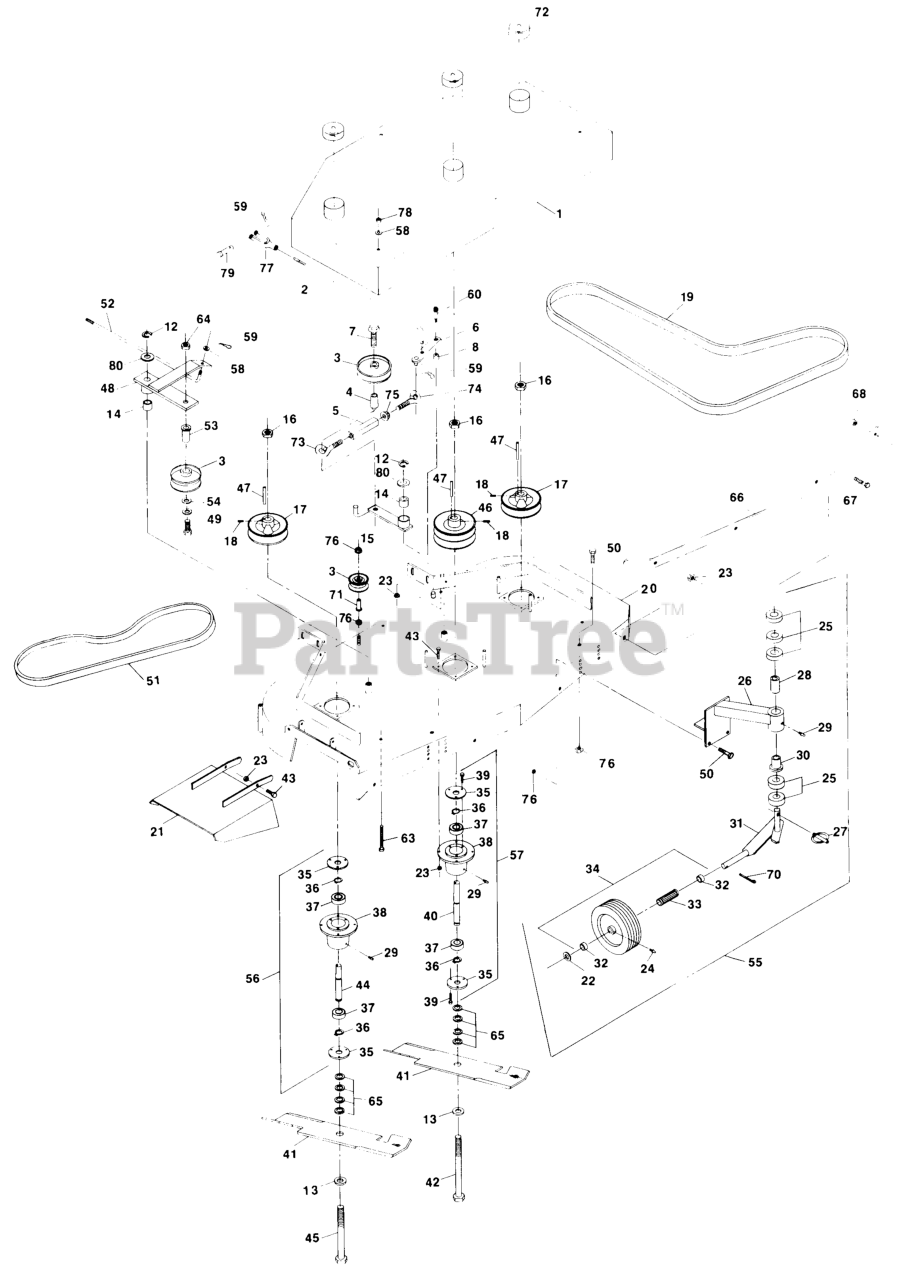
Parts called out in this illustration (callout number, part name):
5	BODY-TURNBUCKLE
14	BEARING,POWDERED METAL
17	PULLEY,CAST IRON
18	SCREW-SET
19	BELT,MAIN DECK
25	SPACER-CASTER
28	BEARING,STRAIGHT
31	WLD,STRUT CASTER
38	HOUSING,CUTTER
39	SCRWMACH PHS
42	SCREW-CAP, HH
44	SPINDLE,CUTTER
48	ARM,IDLER COMPLETE
51	BELT,FRONT DECK
52	ROD,BELT TENSION
56	HOUSING,CUTTER COMPLETE
57	HOUSING,CUTTER COMPLETE
59	PIN-COTTER
60	BOLT,SHLDR KSKH
63	BOLT,TAP HH
72	CAP,SPINDLE GUARD
73	EYEBOLT-THREAD, LH
74	EYEBOLT-THREAD, RH
77	YOKE-ADJUSTABLE
79	PIN-CLEVIS
80	WASHER-SPINDLE
